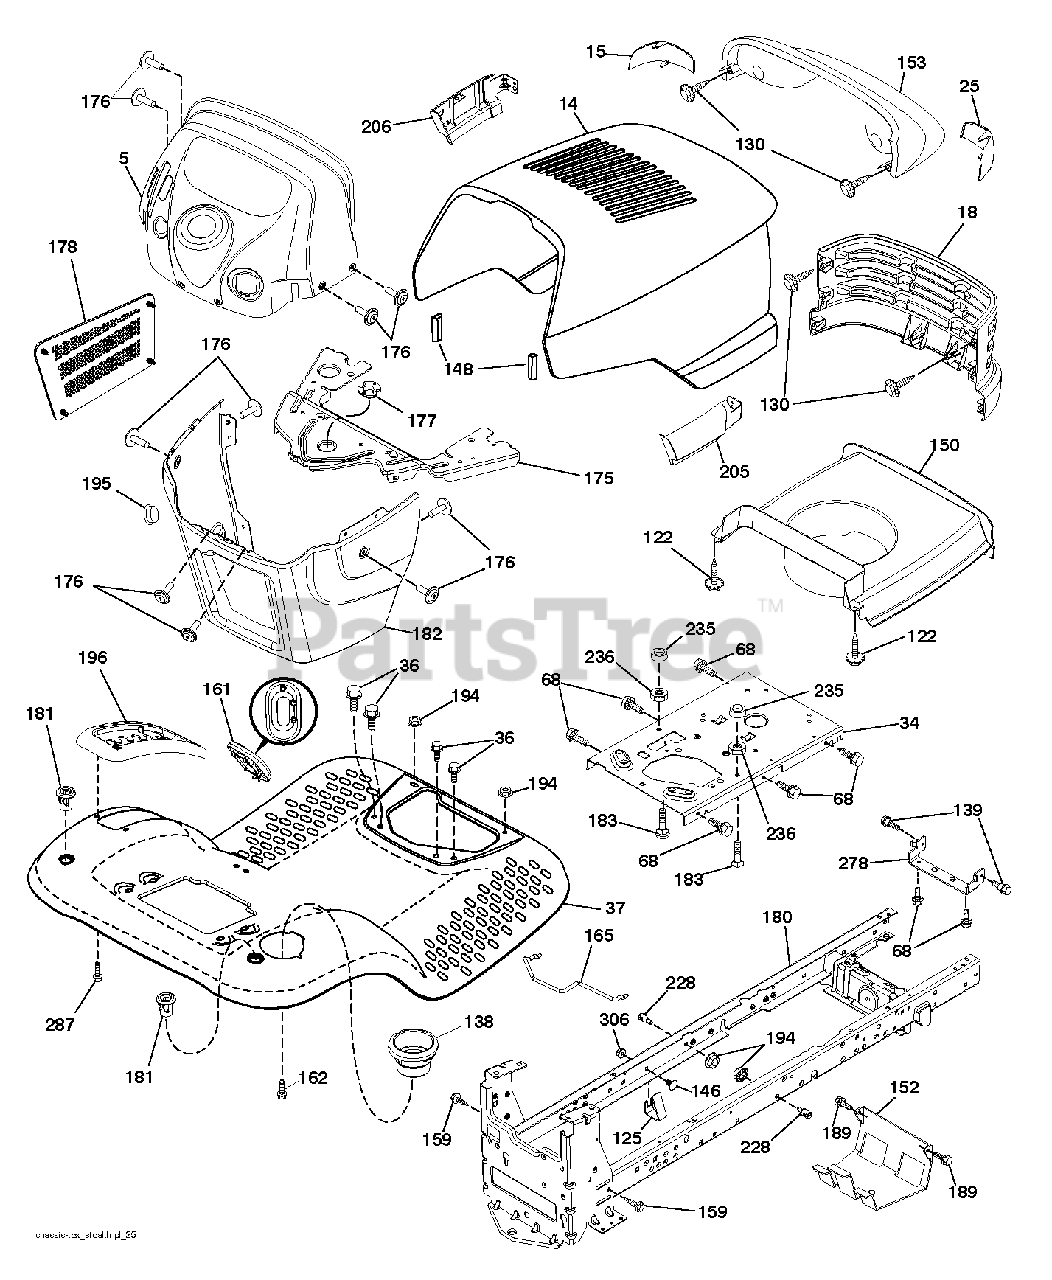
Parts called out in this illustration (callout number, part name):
5	DASH.UPR.STEALTH
15	LENS LH
18	GRILLE.STEALTH.GT.BLACK
25	LENS RH
37	FENDER.TLT.W/CPH.W/FW.666
68	SCREW LT
122	SCREW.WSHD.HEX10-32X5/8
130	SCREW.#10 X 0.750.BOS THREAD
138	CUPHOLDER.TL.TEX.BLACK
148	EXTRUSION BUMPER
150	DUCT HEAT HOOD
152	SHIELD BROWNING
159	SCREW, 3/8-16X3/4
161	WINDOW.FUEL.LT.TEX.BLACK
162	SCREW.HI-LO.CONSOLE
165	SUPPORT.TANK.REAR.W/TE
175	CROSSMEMBER.
176	SCREW.#10-24X5/8.RN.QU
177	BUSHING,STEERING
178	CARGO.ASM.NET.DASH.LOWER
180	CHASSIS
182	DASH.LOWER.
183	BOLT.5/16-18X1-1/4 FULL THD
194	NUT LOCK HEX FLANGE 5/16-18
196	CONSOLE.ASM.DECKLFT.BL/RBT.TLT
205	SKIRT.GRILLE.STEALTH.RH
206	SKIRT.GRILLE.STEALTH.LH
228	STUD.FASTNER.W/ANTI-ROTATE
235	SPACER FENDER
236	NUT.CENTERLOCK.5/16-
278	BRKT.HOOD/MUFF.STEALTH
